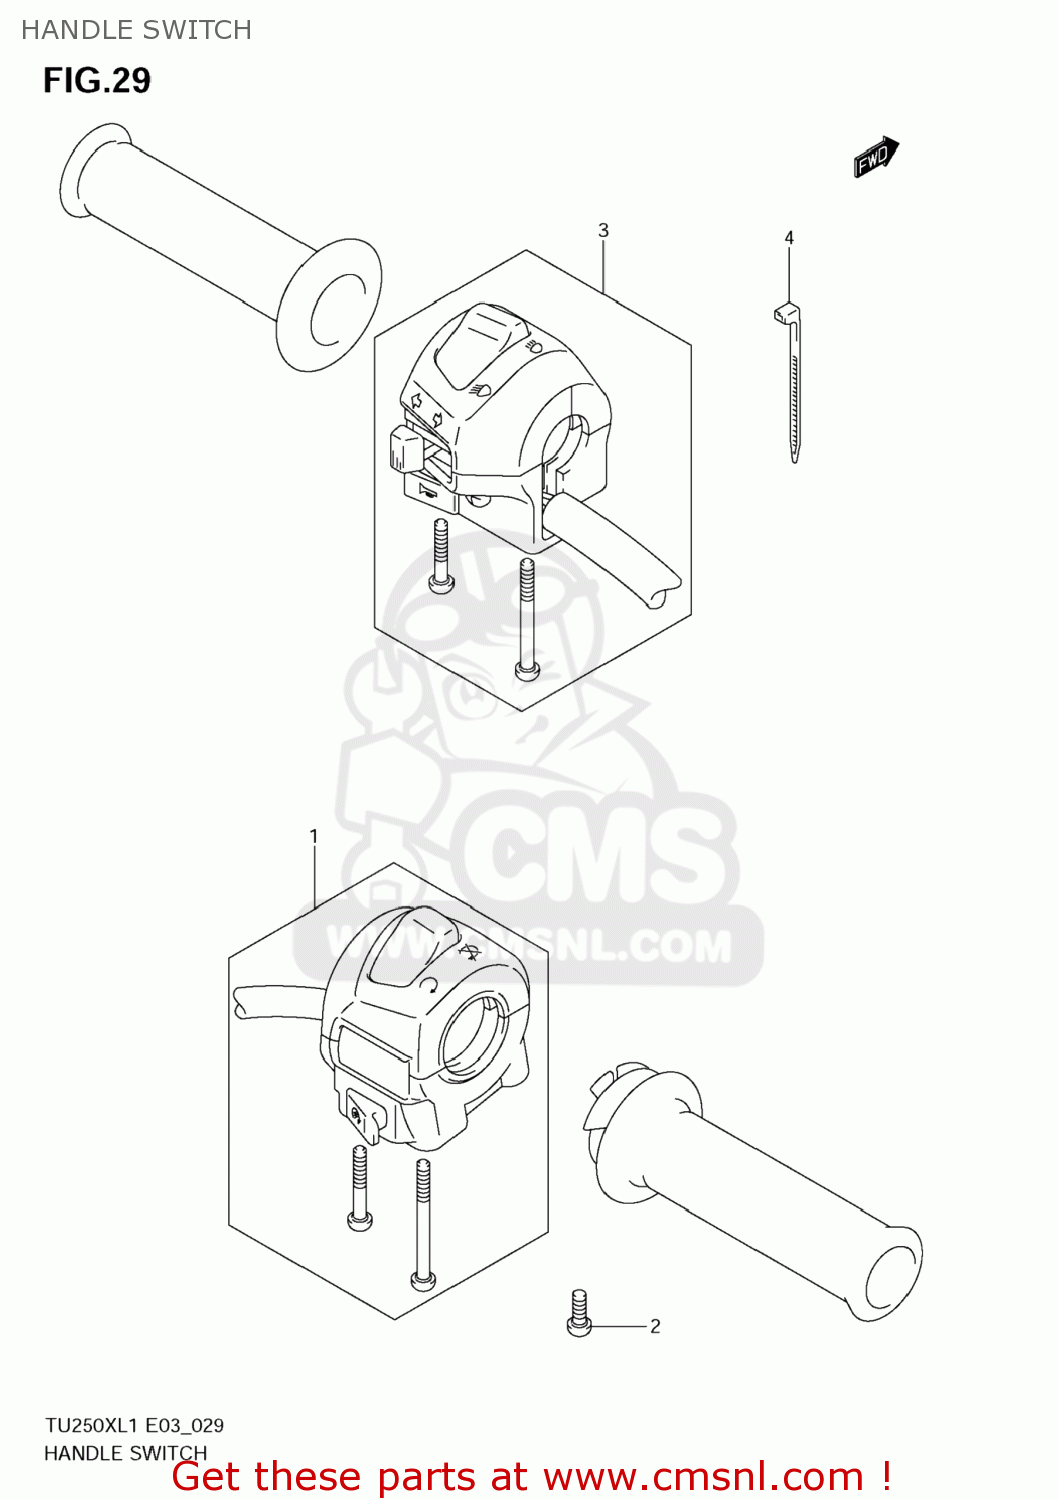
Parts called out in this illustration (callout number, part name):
1	SWITCH ASSY,HA
2	SCREW
3	SWITCH ASSY,HANDLE,L
4	CLAMP(L:145)
